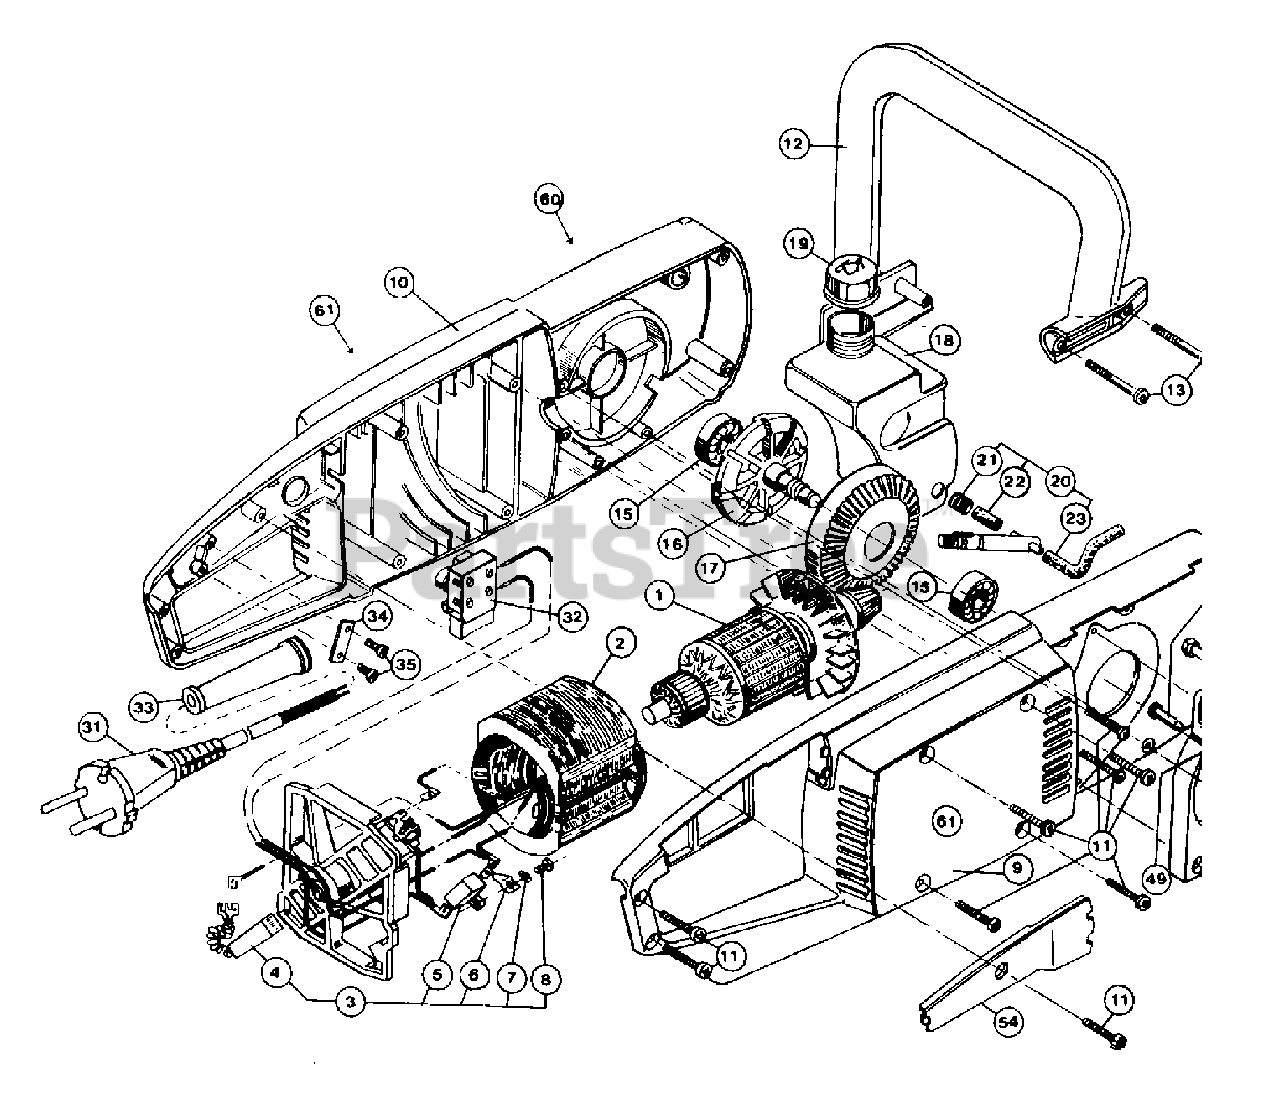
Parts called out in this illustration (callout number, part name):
1	ARMATURE 220V
2	FIELD COIL 220V
3	BRUSH HOLDER ASS'Y NLA
4	CARBON BRUSH
5	CAPACITOR
7	LOCK WASHER 4.3X8
8	SCREW RXS B8X9.5
9	MOTOR HOUSING R.
10	MOTOR HOUSING L.
12	FRONT HANDLE NLA
15	BALL BEARING
16	DRIVE SHAFT
17	GEAR WHEEL
18	OIL TANK NLA
19	TANK CAP
20	OIL PUMP COMPL.
21	OIL FILTER
24	CLUTCH COMPL.
26	RETAINING RING
27	CHAIN COVER
28	NUT M6M M6
31	CABLE W PLUG
32	SWITCH W/ CATCH
34	CABLE CLAMP
36	CHAINBRAKE COMPL. NLA
37	CHAIN CATCHER
41	RELEASE LEVER
42	BRAKE BAND
44	SCREW MCS 5X40
54	HANDLE FILLER
62	FRIKTION BAND
66	CLUTCH DRUM
67	NEEDLE BEARING
5080302-02	ARMATURE 240V
5080302-10	FIELD COIL 220V
5080339-01	CABLE W/ PLUG NLA
5080340-02	CABLE W/ PLUG
5080340-03	CABLE W/ PLUG
5080340-05	CABLE WITH PLUG NLA
